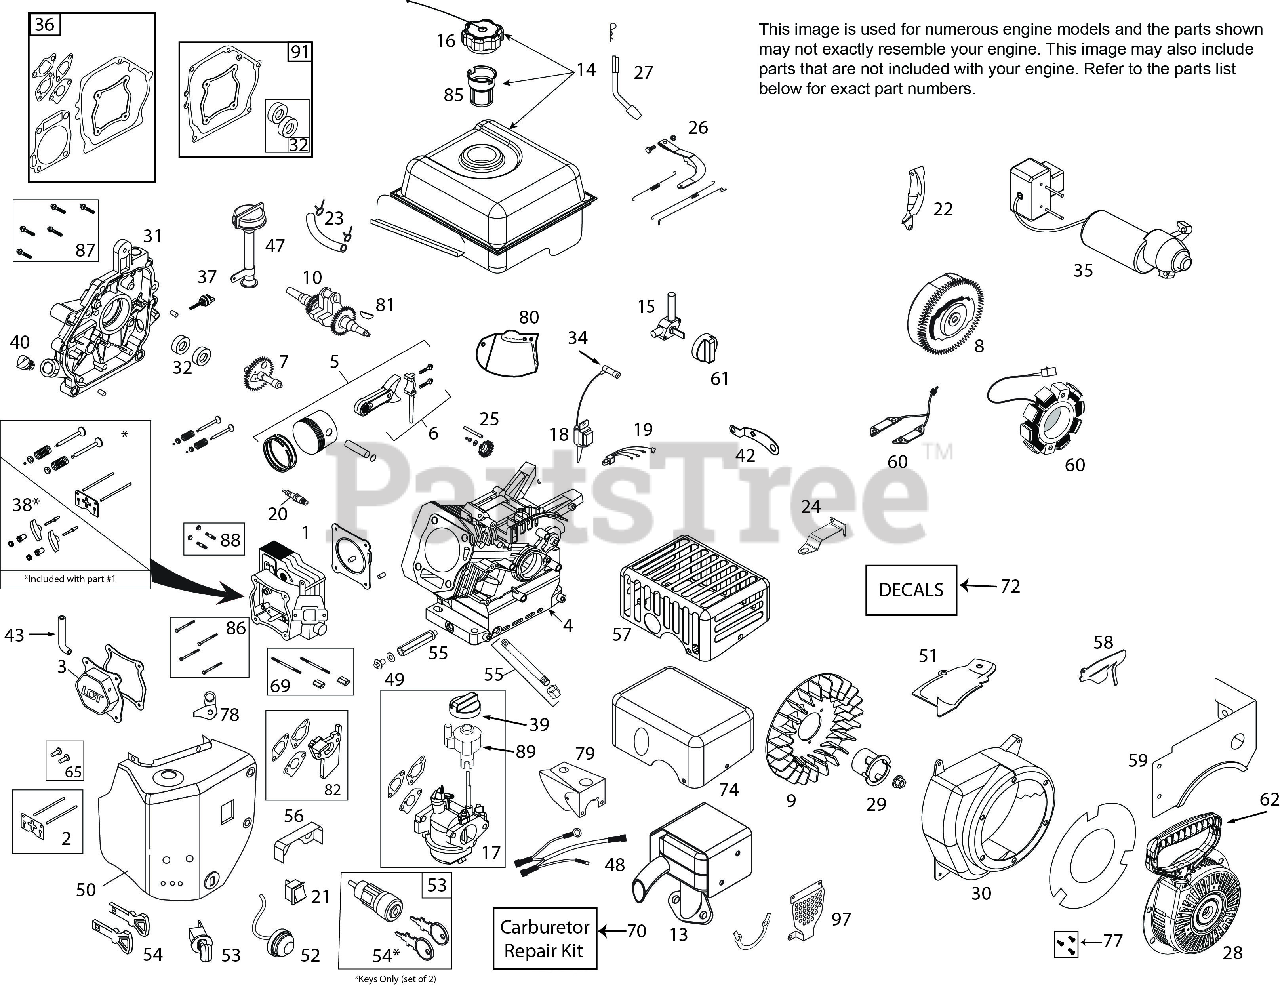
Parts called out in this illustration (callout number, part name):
1	CYLINDER HEAD ASSY(W/GASKET)
2	PUSH ROD & PLATE KIT(W/GASKET)
3	VALVE COVER (W/GASKET)
5	PISTON & ROD ASSEMBLY
7	CAMSHAFT - MCR(W/COVER GASKET)
8	FLYWHEEL - ELECTRIC START
9	COOLLNG FAN - FLYWHEEL (PLSTC)
10	CRANKSHAFT (#18 KEYED)
13	MUFFLER KIT
14	FUEL TANK W/PLASTIC CAP
15	FUEL TANK ON/OFF VALVE
16	CAP, FUEL TANK BLACK
17	CARBURETOR (W/GSKTS & SPACER)
18	IGNITION COIL (CDI) (STANDARD)
20	SPARK PLUG, ARIENS AX
22	SHIELD - FLYWHEEL - MNL START
23	FUEL HOSE KIT 1/4-318MM
24	SPEED CONTROL BRACKET (FIXED)
25	GOVERNOR GEAR ASSEMBLY
26	GOVERNOR ARM & LINK KIT
27	GOVERNOR ARM PADDLE
28	RECOIL STARTER SSTAGE 78" ROPE
29	STARTER CUP
30	BLOWER HSG BLACK MANUAL START
31	CRANKCASE COVER ASSY
32	OIL SEAL KIT
34	SPARK PLUG BOOT (W/MTL SHIELD)
35	120V ELECTRIC STARTER
35	STARTER SWITCH SCREWS
36	ENGINE GASKET KIT
37	SMALL BLACK OIL DIPSTICK
38	ROCKER ARM KIT (W/GASKET)
39	CHOKE CONTROL KNOB (RED)
43	BREATHER TUBE
48	WIRE HARNESS
49	OIL DRAIN PLUG (W/WASHER)
50	HEATER BOX ASSY
51	SHIELD - CYLINDER
52	PRIMER BULB WITH HOSE-SNOW (RED)
53	KEY SWITCH, STOP-RUN (W/KEYS)
54	KEY SET (2) (RED)
55	OIL DRAIN TUBE
57	CE COMPLIANT MUFFLER SHIELD
58	SHIELD - GOVERNOR LINKAGE
59	FUEL TANK SKIRT
61	FUEL CONTROL KNOB (RED)
62	STARTER GRIP
65	TAPPET KIT (SET OF 2)
69	CARBURETOR STUDS & COUPLNG KIT
70	CARBURETOR REPAIR KIT
72	ARIENS 136 (ALL) DECAL KIT
74	MUFFLER HEAT SHIELD COVER
77	RECOIL BOLT KIT
78	BREATHER TUBE BRACKET
79	CARBURETOR COVER
80	TOP SHIELD
81	WOODRUFFF FLYWHEEL KEY 5-PACK
82	CARBURETOR SPACER
85	FUEL TANK STRAINER
86	HEAD BLT KIT 136-179-208-254CC
87	CRANKCASE COVER BOLT KIT 136CC
88	MUFFLER MTG STUD KIT
91	CRANKCASE GASKET KIT (136CC)
9999	HIGH ALT JET - 136CC L13 CARB
9999	HARDWARE KIT (4 M6X10 FLG BLT)
